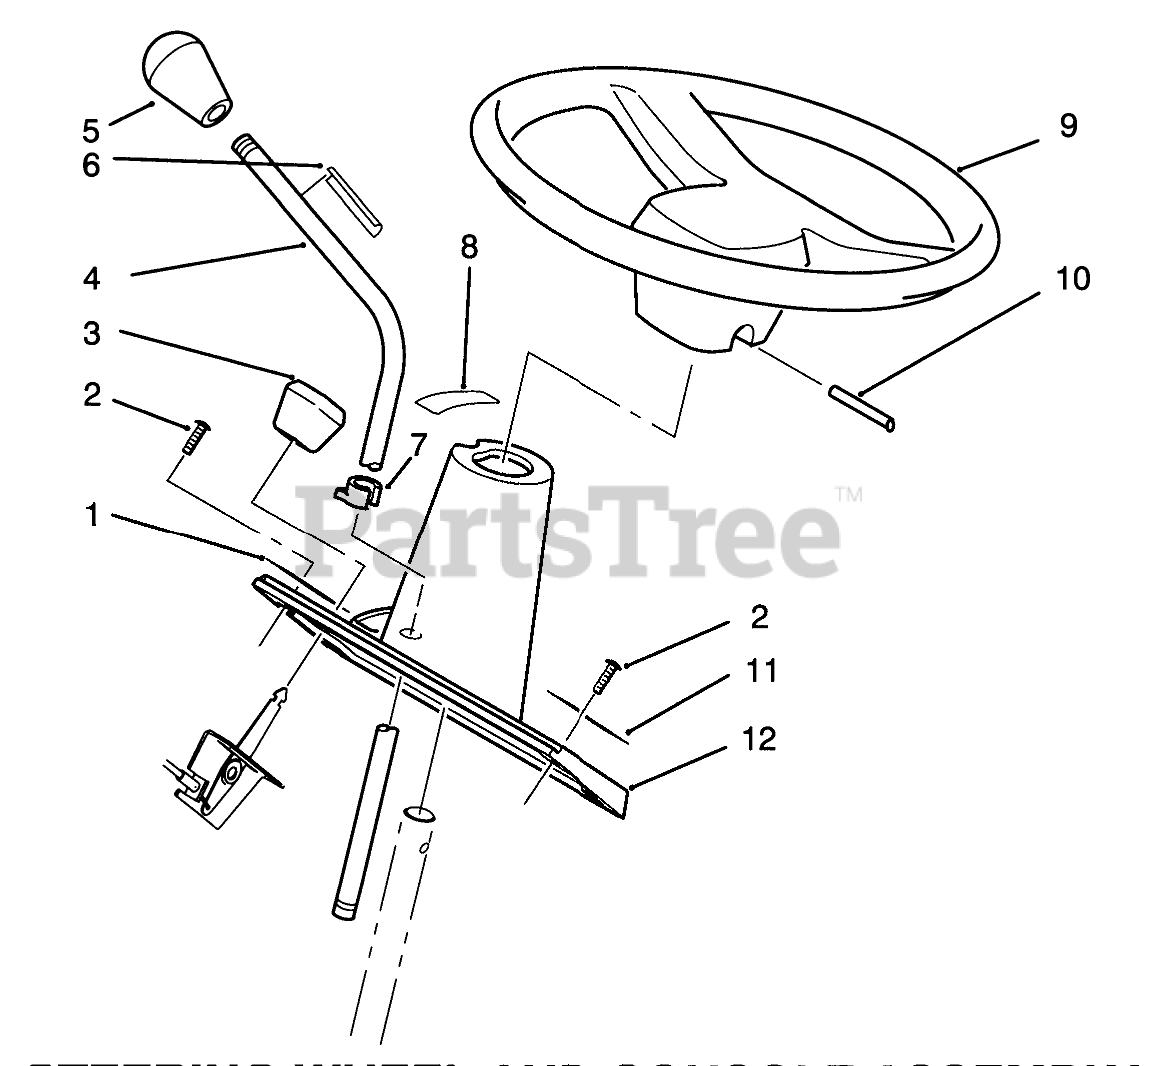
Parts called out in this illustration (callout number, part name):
1	DECAL-THROTTLE
2	SCREW
3	KNOB-THROTTLE
4	ROD-SHIFT LEVER
6	DECAL-MOTION CONTROL
7	POINTER
8	DECAL-HYDRO MOTION
9	Steering Wheel
10	PIN-ROLL
11	Decal-Height of Cut
12	CONSOLE
